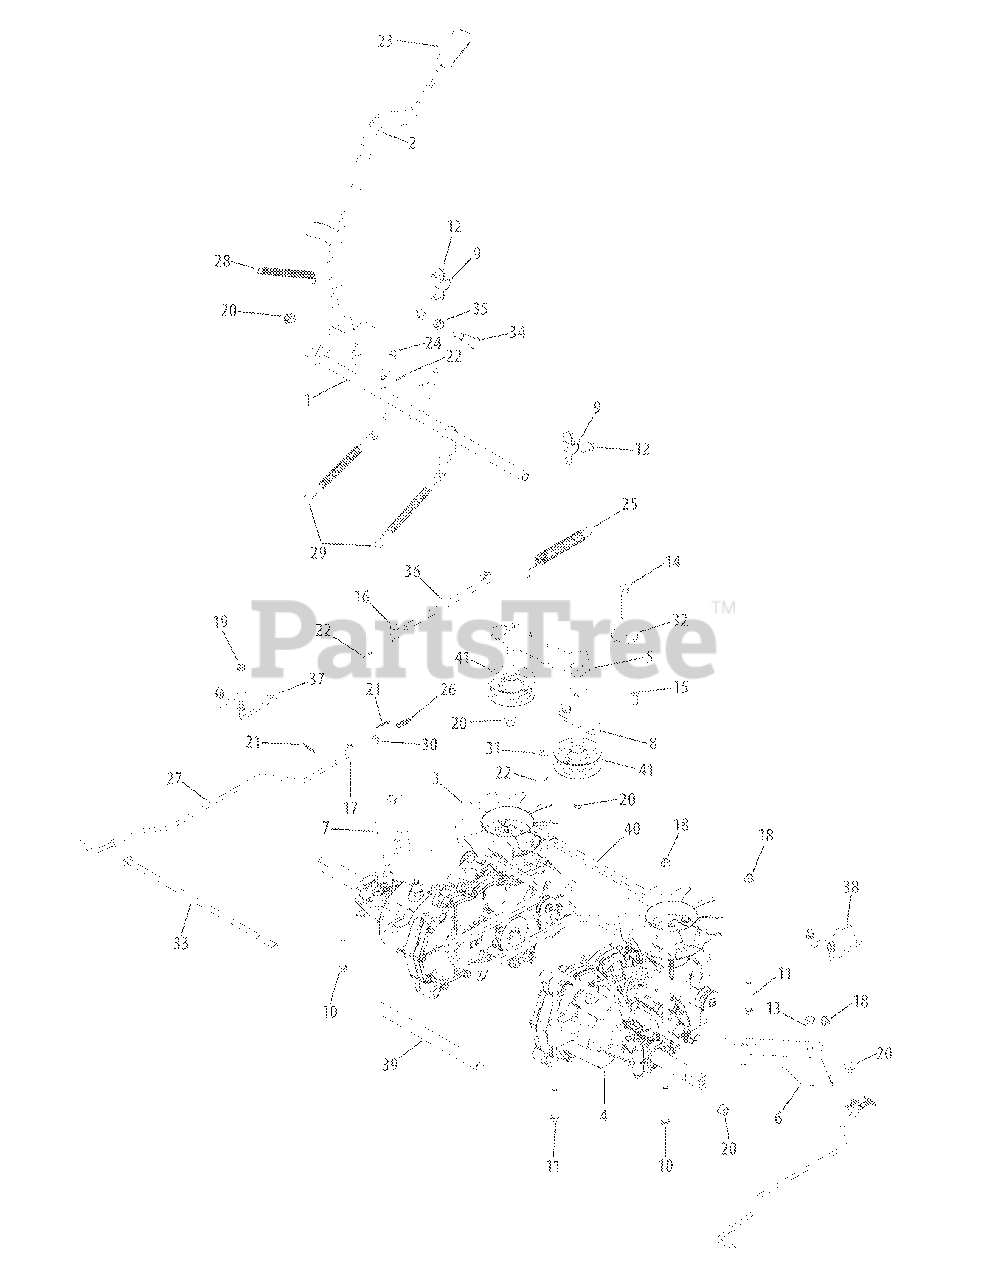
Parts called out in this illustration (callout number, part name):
1	Brake Shaft Assembly
2	Brake Handle Assembly
3	LH Transmission Assembly
4	RH Transmission Assembly
5	Idler Bracket
6	RH Mount Bracket
7	LH Mount Bracket
8	Idler Mount Plate
9	Shaft Mount Bracket
10	Hex Screw, 5.16-18 x 2.75
11	Hex Screw, 5.16-18 x 2.25
12	Hex Washer Screw, 5.16-18 x .750
13	Hex Screw, 3.8-16 x 1.00
14	Hex Screw, 3.8-16 x 2.25
15	Hex Screw, 5.16-18 x .875
16	Ferrule, 3.8-24 x .375
17	Ferrule, .325 x .312
18	Flange Lock Nut, 5.16-18
19	Flange Lock Nut, 1.4-20
20	Flange Lock Nut, 3.8-16
21	Cotter Pin, .072 x 1.13
22	Cotter Pin, 3.32 x .750
23	Selector Handle
24	Extension Spring, .48 x 2.03
25	Extension Spring, .75 x 6.02
26	Compression Spring, .34 x 1.0
27	Transmission Bypass Lever Wire
28	Extension Spring, .50 x 6.37
29	Extension Spring, .500 x 7.0
30	Spring Washer, .265 x .562 x .025
31	Thrust Washer, .375 x .70 x .030
32	Shoulder Spacer, .884 x .190
33	Rod, .328 x 14.00
34	Shoulder Screw, .498 x 1.635
35	Flange Bearing, .500 x .34
36	Disengage Brake Rod
37	LH Keeper Rod
38	RH Keeper Rod
39	Transmission Spacer, 9.40
41	Flat Idler Pulley, 2.75
